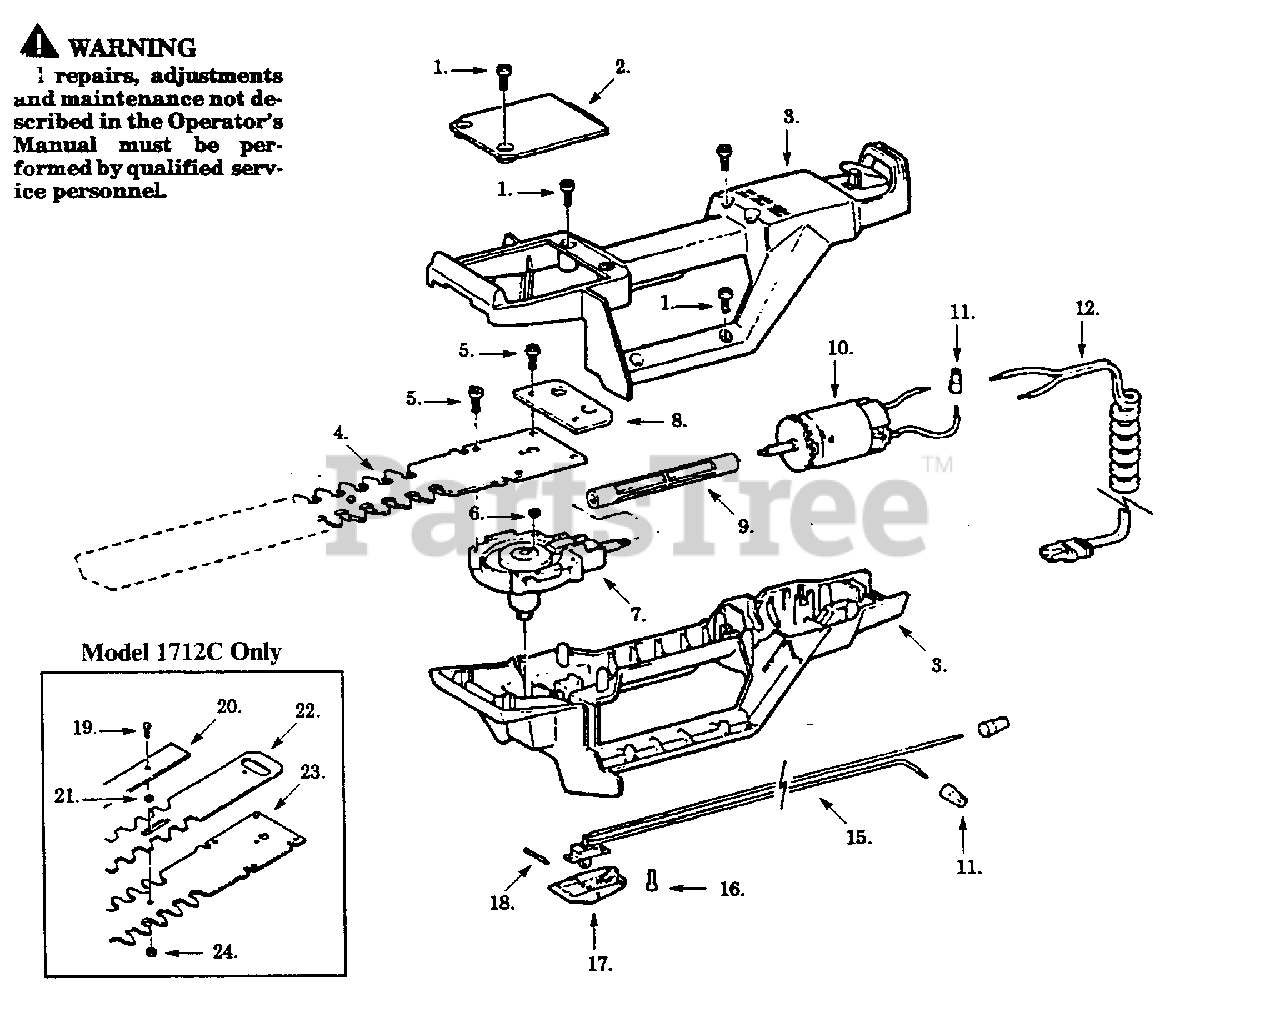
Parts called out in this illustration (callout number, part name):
2	Gear Box Cover
3	Housing Set
4	Blade Ass'y.
7	Gear Box Ass'y.
9	Drive Shaft
10	Motor/Fan Ass'y.
11	Wire Nut
12	Power Cord
15	Switch/Wire Ass'y.
17	Switch Cap
18	Groove Pin
20	Retaining Plate
22	Cutting Blade
23	Stationary Blade
